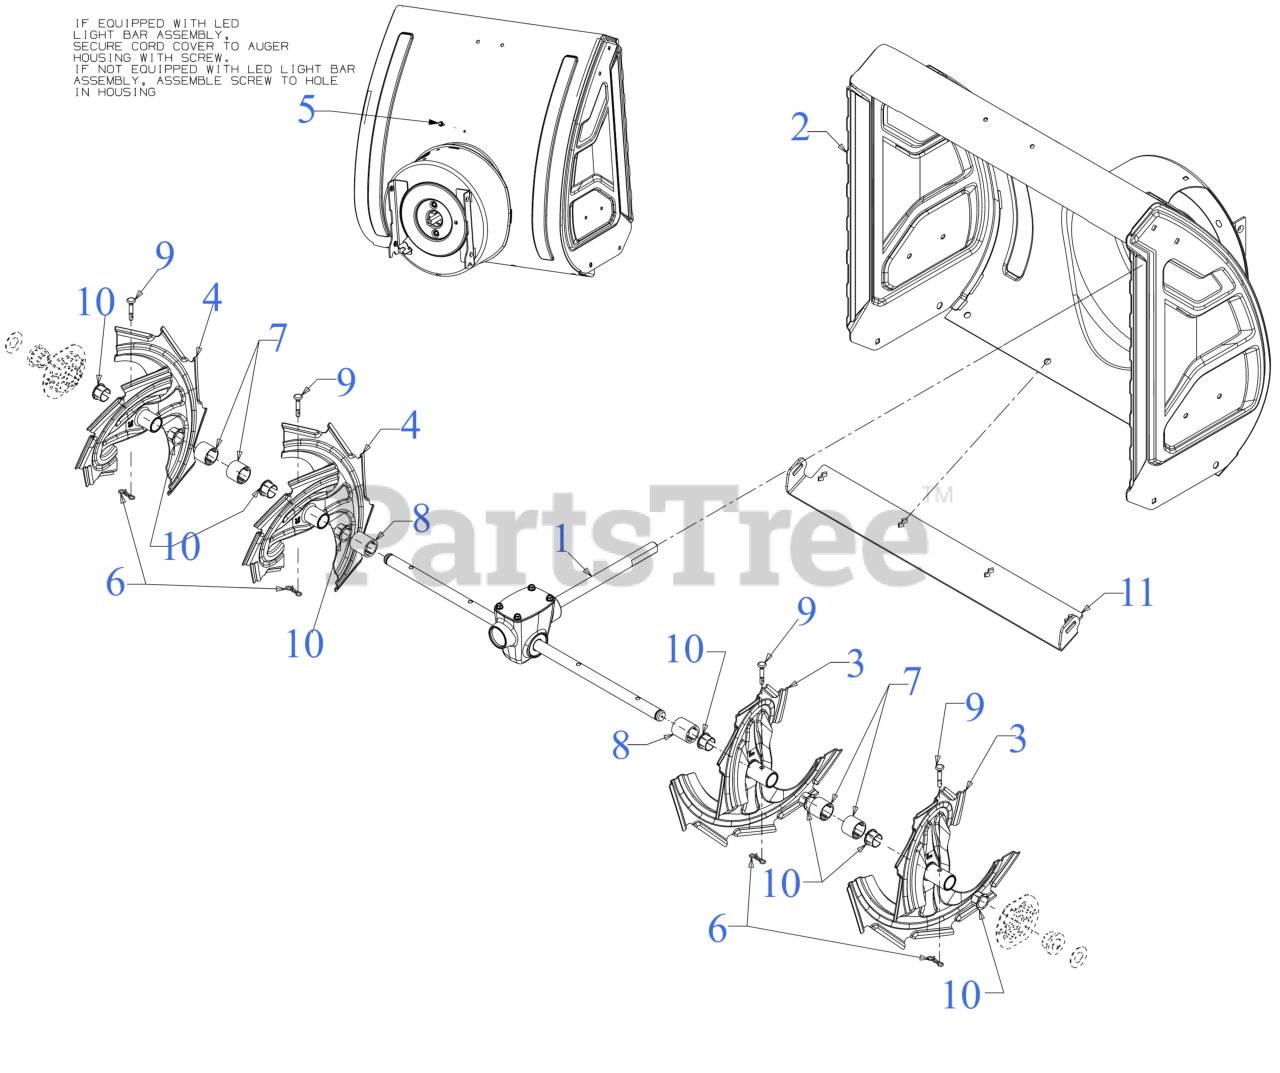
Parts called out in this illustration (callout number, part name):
1	GEARBOX ASSEMBLY 26" 2X HD
2	26" AUGER HOUSING
3	10T AUGER SPIRAL (LH)
4	10T AUGER SPIRAL (RH)
5	SCREW M6-1 x .625
6	BOW TIE COTTER PIN 1/4-5/16
7	SPACER 1.25OD x .75ID X1.00 LG
8	SPACER 1.25OD x .75ID x 1.312 LG
9	SHEAR PIN .25 x 1.50 GR2
10	FLANGE BUSHING
